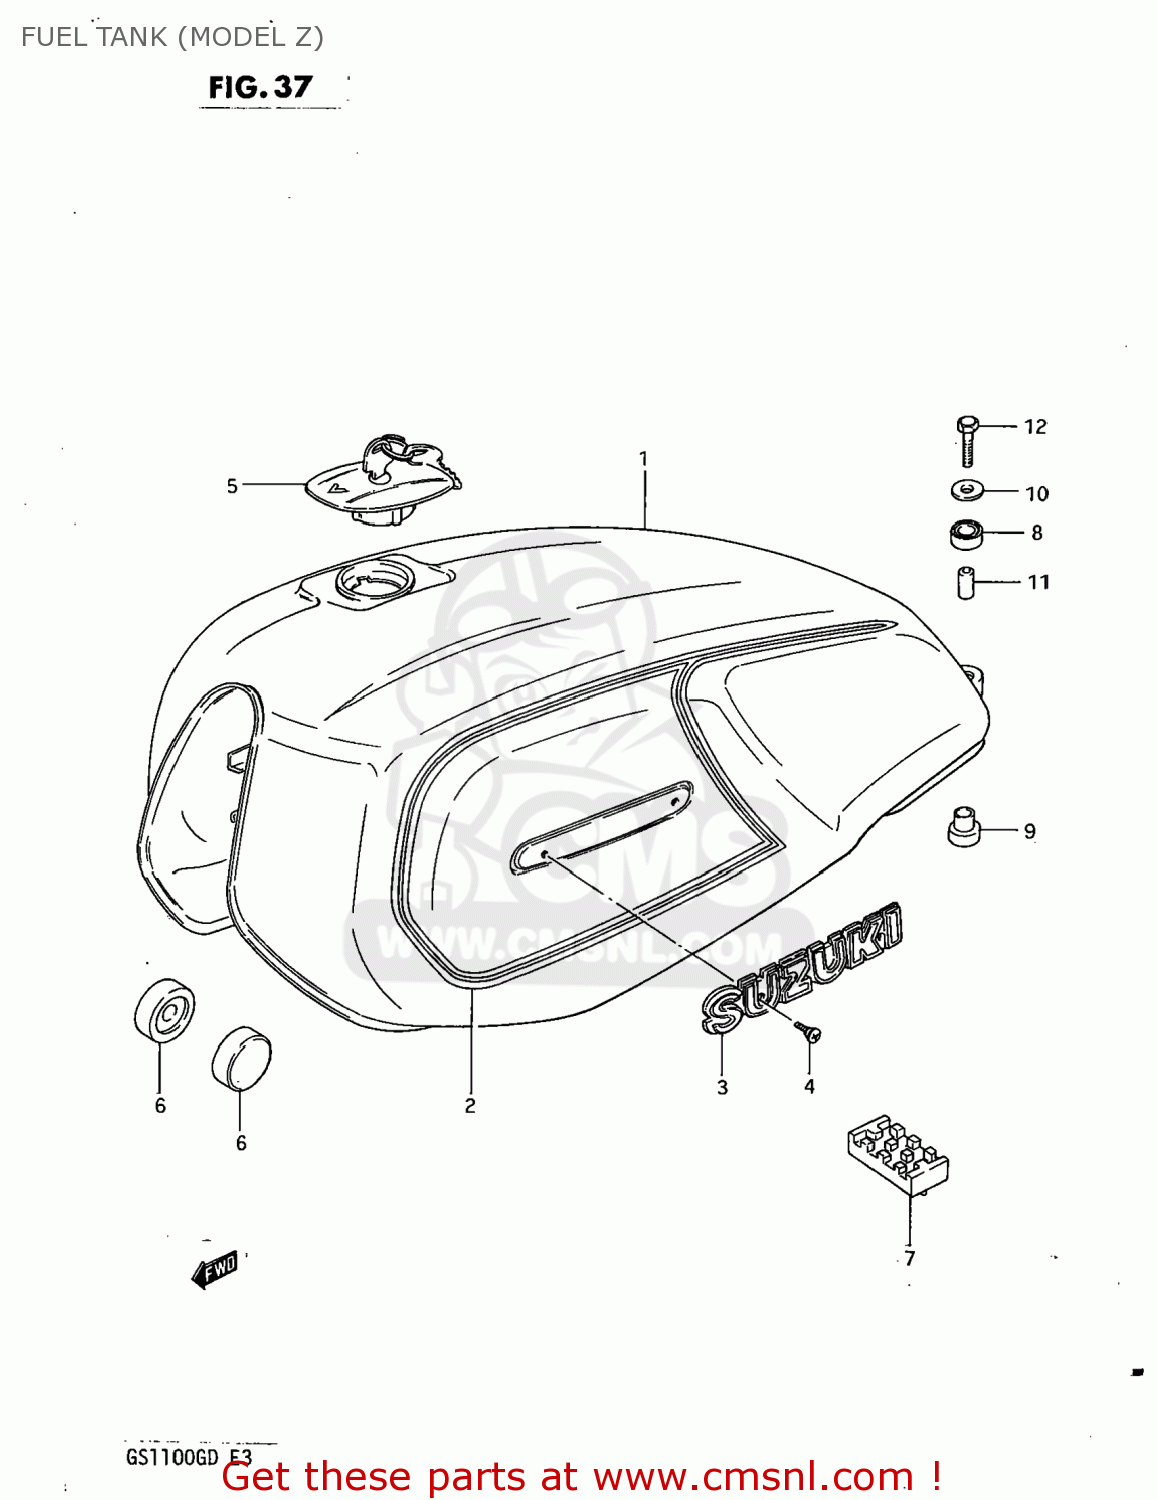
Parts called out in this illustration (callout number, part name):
1	TANK ASSEMBLY,FUEL
2	TAPE SET,FUEL TANK
3	EMBLEM
4	SCREW 3X6
5	CAP SET,FUEL TANK
6	CUSHION
7	CUSHION,FUEL TANK
8	CUSHION
9	CUSHION
10	WASHER (6.5X24X1.6)
11	SPACER (6.4X9X21.5)
12	BOLT
